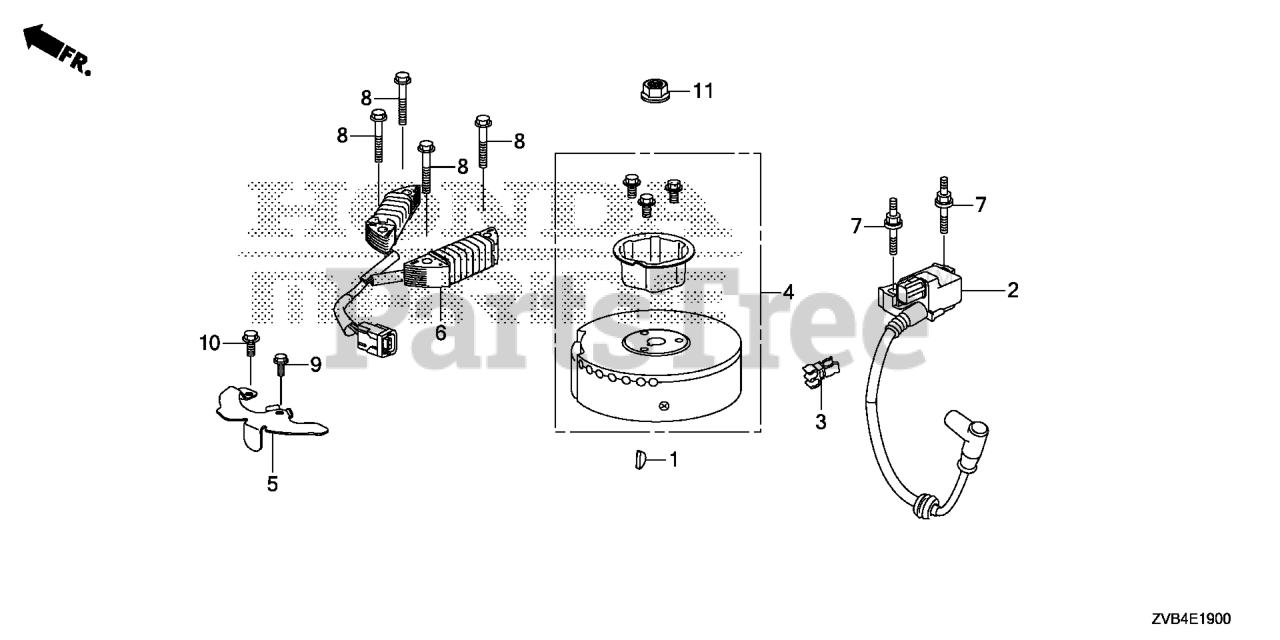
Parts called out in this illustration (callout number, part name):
1	KEY, SPECIAL WOODRUFF (25X18)
2	COIL ASSY., IGNITION
3	CLIP, IGNITION WIRE
4	FLYWHEEL *BLACK* (BLACK)
5	CLAMP, WIRE
7	BOLT, SPECIAL (6MM)
9	BOLT, FLANGE (5X10)
10	BOLT, FLANGE (6X12)
11	NUT, SPECIAL (14MM)
